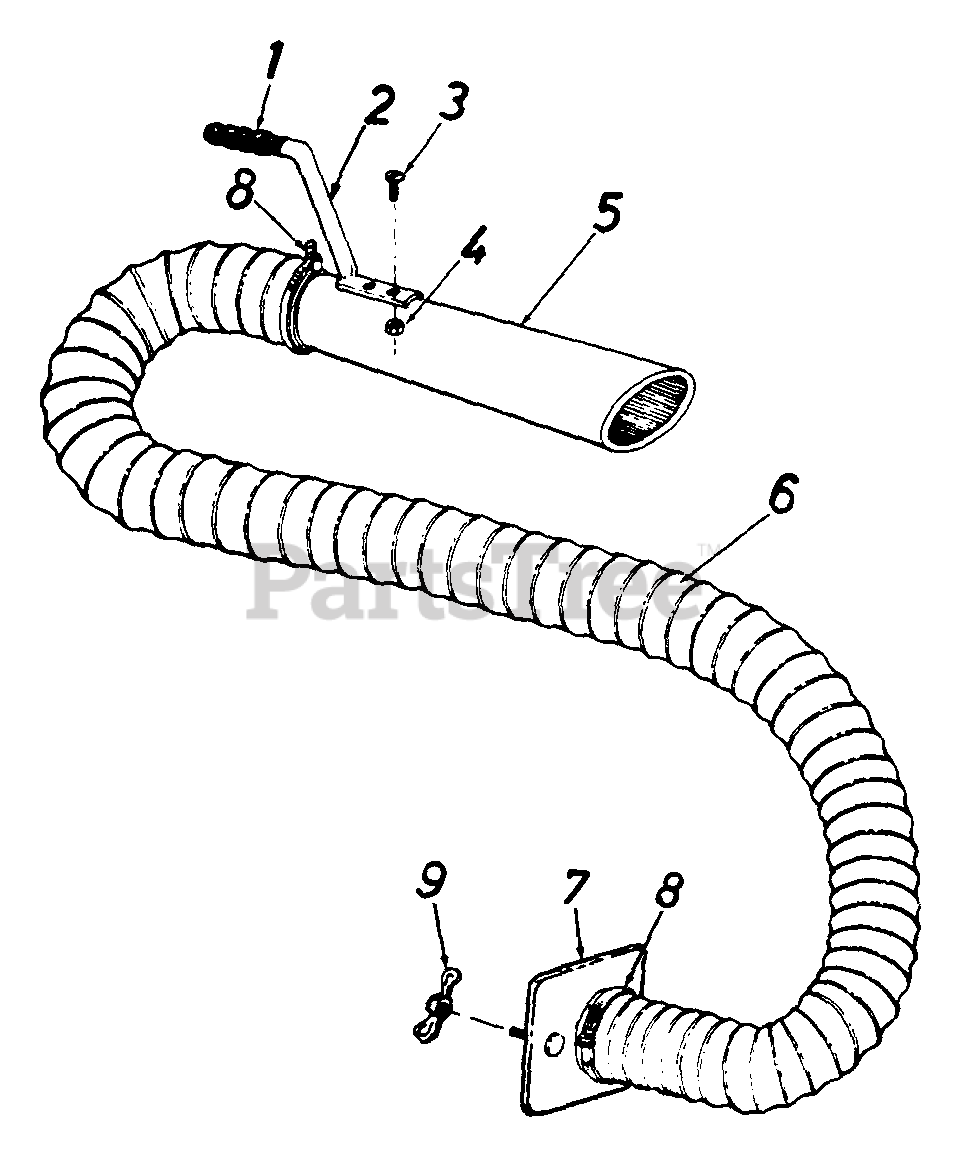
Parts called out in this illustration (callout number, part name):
1	Handle Grip
2	Handle
3	Truss Sems Scr. 10-24 x 1/2" Lg.
4	Hex Nut 10-24 Thd.
5	Hose Nozzle
6	Flexible Hose 4" Dia. x 10'
7	Hose Adapter Plate
8	Hose Clamp - 4"
9	Wing Nut 1/4-20 Thd.
